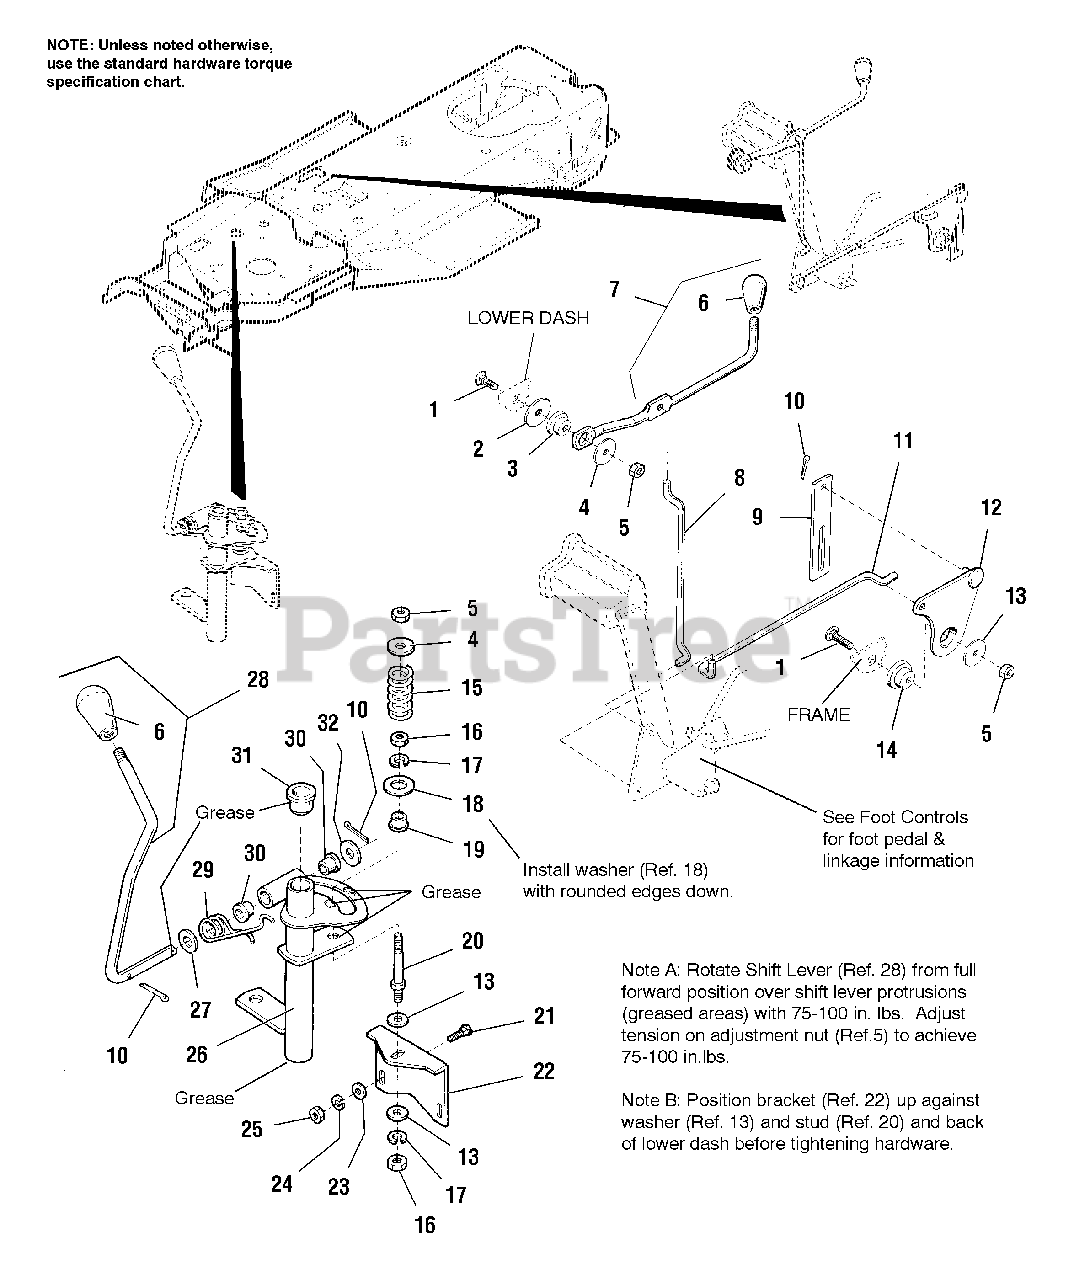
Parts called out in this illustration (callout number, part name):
1	CARRIAGE BOLT, 5/16-18 x 1-1/2
2	WASHER, Plain, 13/32 x 1-1/2 x 1/8
3	SPACER
4	WASHER, Plain, 5/16
5	NUT, Hex, Esna, Lock, 5/16-18
6	KNOB, Plastic
7	ROD, Lift Handle
8	LINK, Lift Upper
9	LINK, Lift, Upper Transport
10	COTTER PIN
12	CAM, Lift Assy.
13	WASHER, Plain, 21/64 x 1-1/4
14	SPACER
15	SPRING, Compression
16	NUT, Hex, 5/16-18
17	LOCKWASHER, 5/16
18	WASHER, 1/2
20	STUD, 5/16-18 x 3-1/4
21	CARRIAGE BOLT, 1/4-20 x 3/4
22	BRACKET, Tension
23	WASHER, Plain, 1/4
24	LOCKWASHER, 1/4
25	NUT, Hex, 1/4-20
26	SHIFT LEVER ASSY.
27	WASHER, Plain
28	LEVER, Shift
29	SPRING, Torsion
30	BUSHING, Plastic, 1/2 Dia.
31	BUSHING, Nylon, 3/4 Dia.
32	WASHER, 1/2
